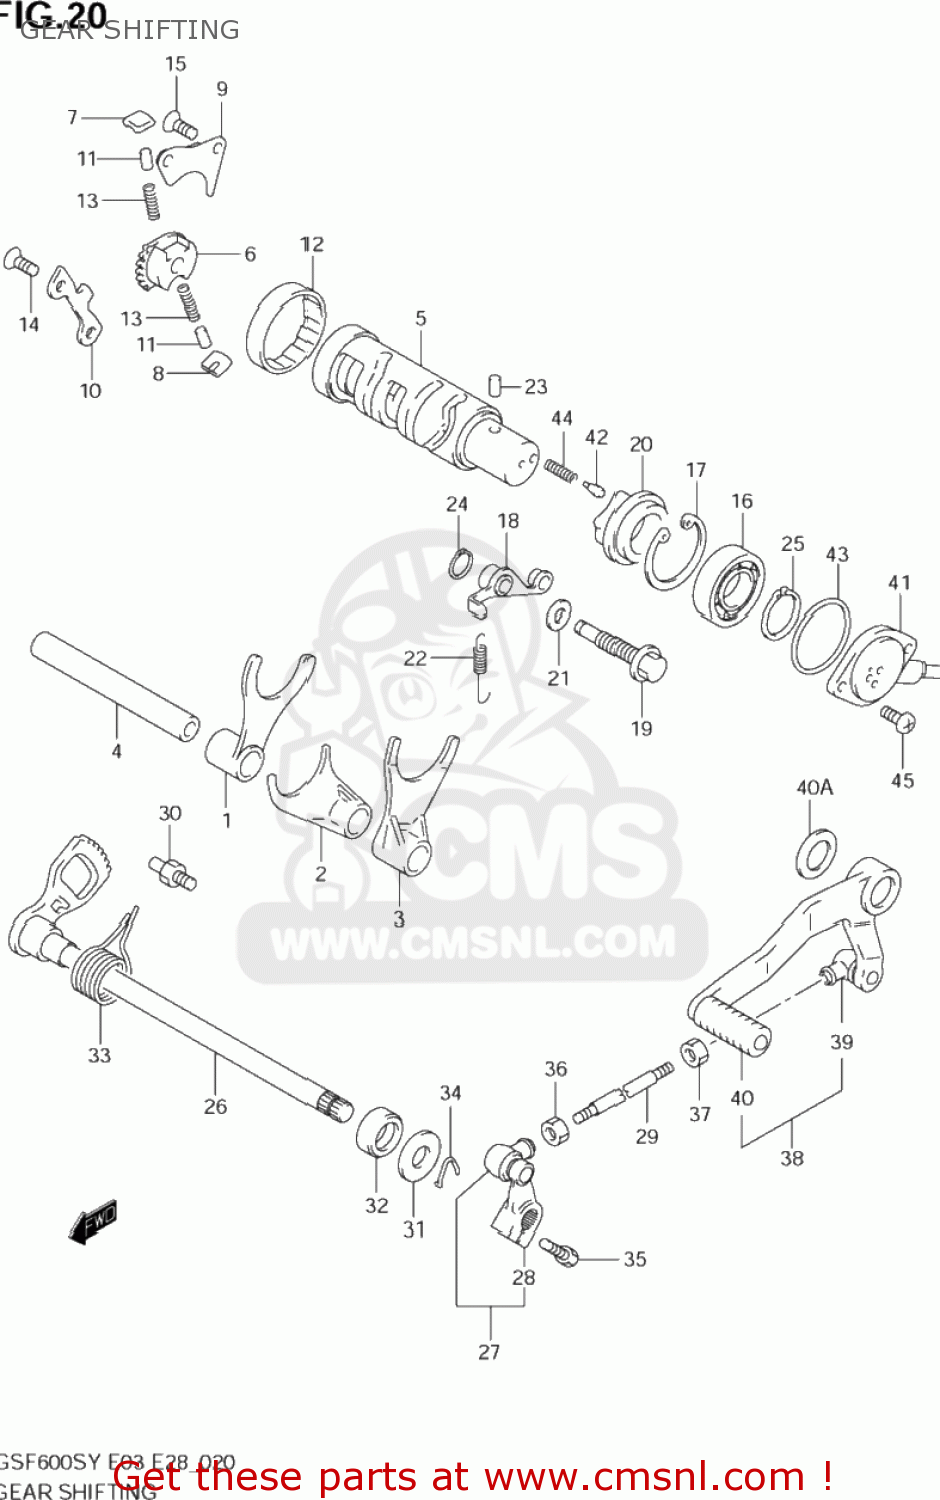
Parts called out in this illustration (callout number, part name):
1	FORK,GEAR SHIFT NO.1
2	FORK,GEAR SHIFT NO.2
3	FORK,GEAR SHIFT NO.3
4	SHAFT,GEAR SHIFT FORK(L:128)
5	CAM,GEAR SHIFT
6	GEAR,GEAR SHIFT CAM DRIVEN
7	PAWL,GEAR SHIFT NO.1
8	PAWL,GEAR SHIFT NO.2
9	LIFTER,GEAR SHIFT PAWL
10	GUIDE,GEAR SHIFT CAM
11	PIN(5X8)
12	BEARING(43X49X12)
13	SPRING
14	SCREW
15	SCREW
16	BEARING
17	CIRCLIP
18	STOPPER,GEAR SHIFT CAM
19	SHAFT,GEAR SHIFT CAM STOPPER
20	PLATE,STOPPER
21	GASKET(10X14X3.6) (NAS)
22	SPRING
23	PIN
24	CIRCLIP
25	CIRCLIP
26	SHAFT,GEAR SHIFT
27	ARM,GEAR SHIFT LINK
28	COVER,DUST
29	ROD,GEAR SHIFT LINK
30	STOPPER,GEAR SHIFT CAM
31	WASHER (12.5X26X1.6)
32	OIL SEAL
33	SPRING
34	CIRCLIP,12 MM
35	BOLT
36	NUT
37	NUT
38	LEVER ASSY,GEAR SHIFT
39	RUBBER,GEAR SHIFT PEDAL
40	COVER,DUST
40A	WASHER(18.2X27X1)
41	BASE ASSY,GEAR SHIFT TERMINAL
42	PIN(5X15.5)
43	O RING(D:2.4,ID:35.5)
44	SPRING
45	SCREW
